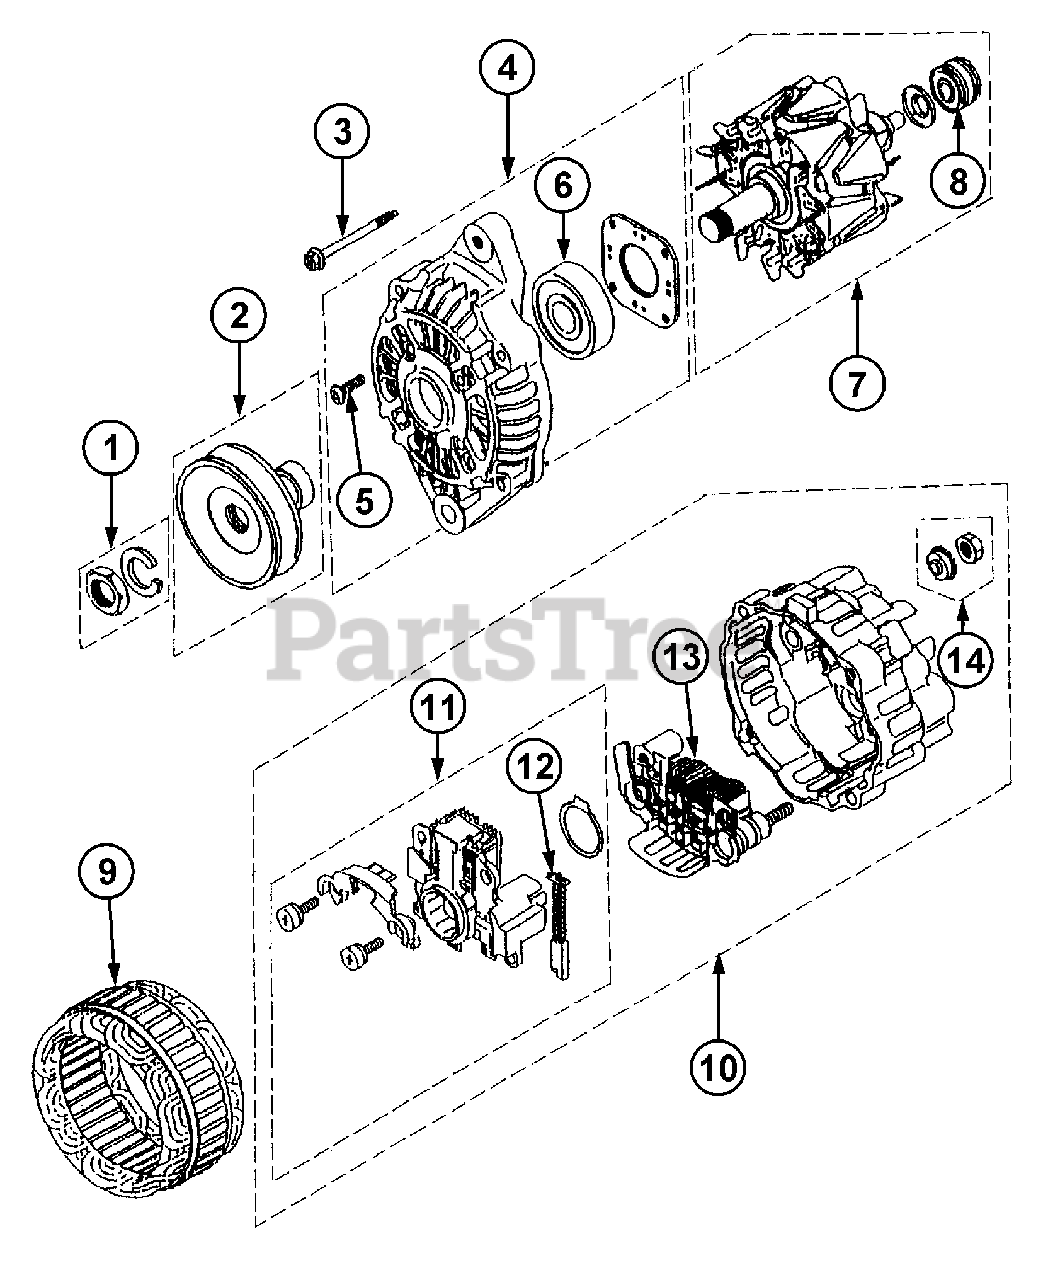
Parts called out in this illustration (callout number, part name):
1	Nut Set
2	Pulley Assy
3	Bolt Set, Thru
4	Bracket Assy, Front
6	Bearing, Front
8	Bearing, Rear
10	Bracket Assy, Rear
11	Regulator Set
13	Rectifier Assy
14	Nut Set
